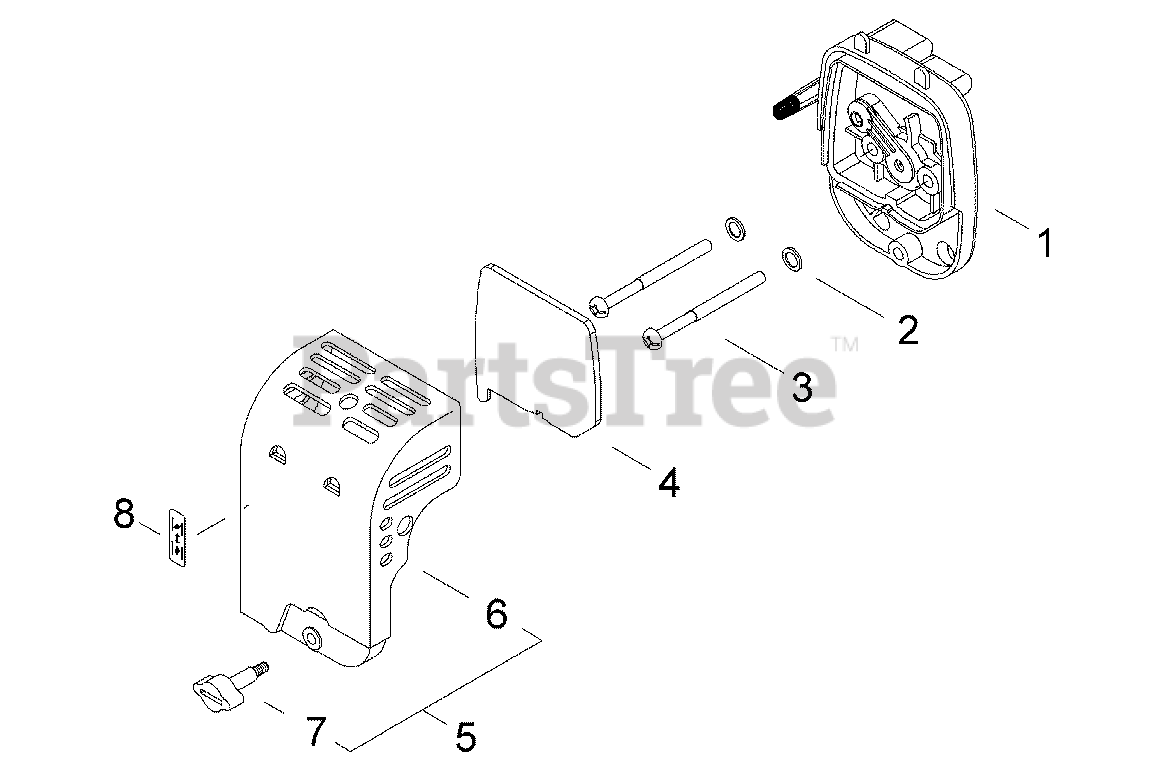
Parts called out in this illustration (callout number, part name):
1	BASE ASSY, AIR FILTER
2	WASHER 5 MM
3	SCREW M5×60
4	FILTER, AIR
5	COVER ASSY, AIR FILTER
6	COVER, AIR FILTER
7	THUMBSCREW M5
8	LABEL, CHOKE
